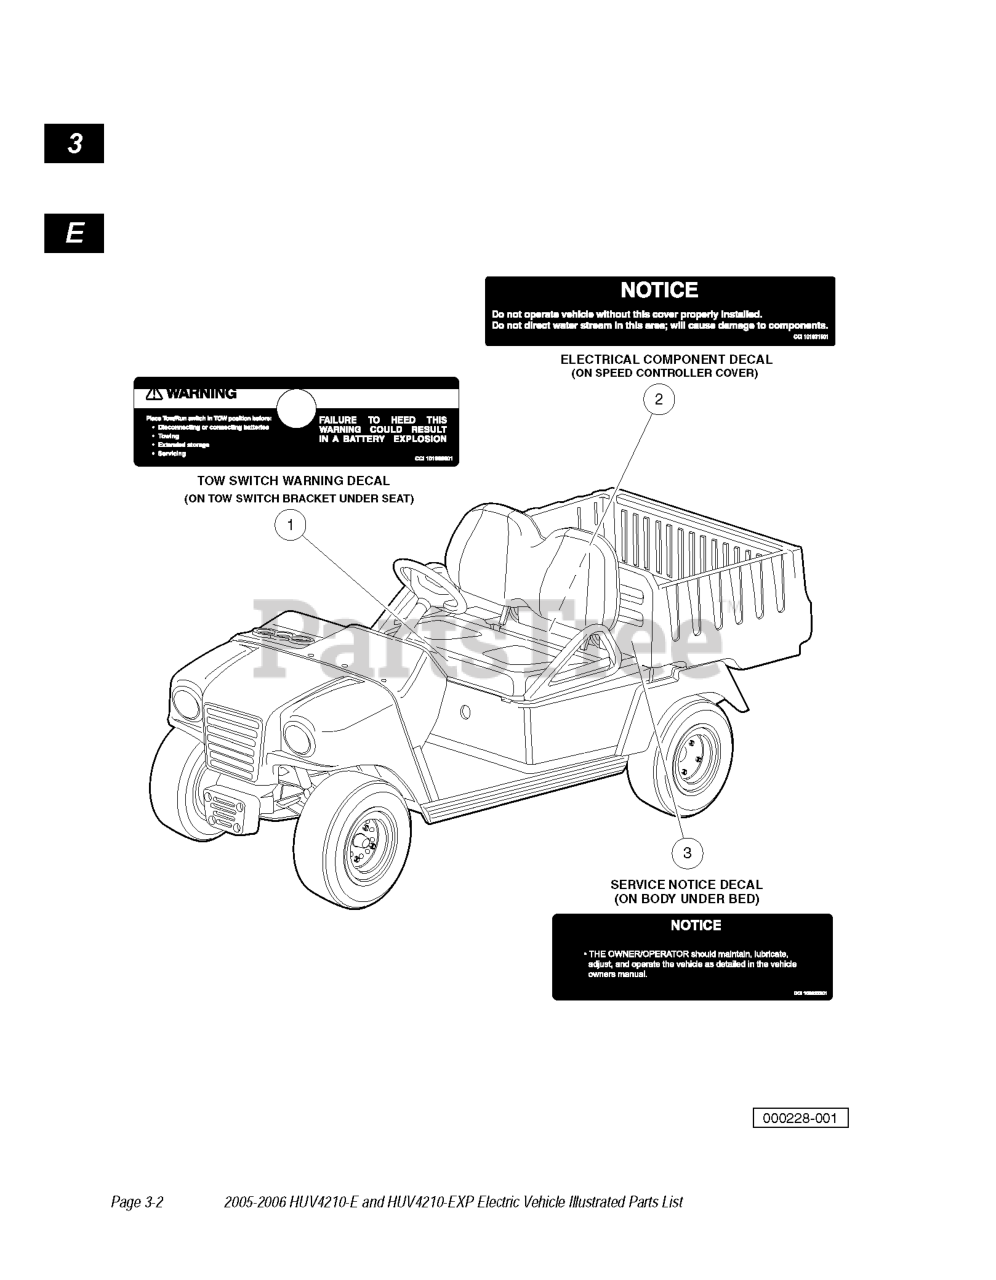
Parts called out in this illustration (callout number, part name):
1	DECAL, TOW SWITCH WARNING
2	DECAL, COMPONENT COVER
3	DECAL, MAINENANCE
